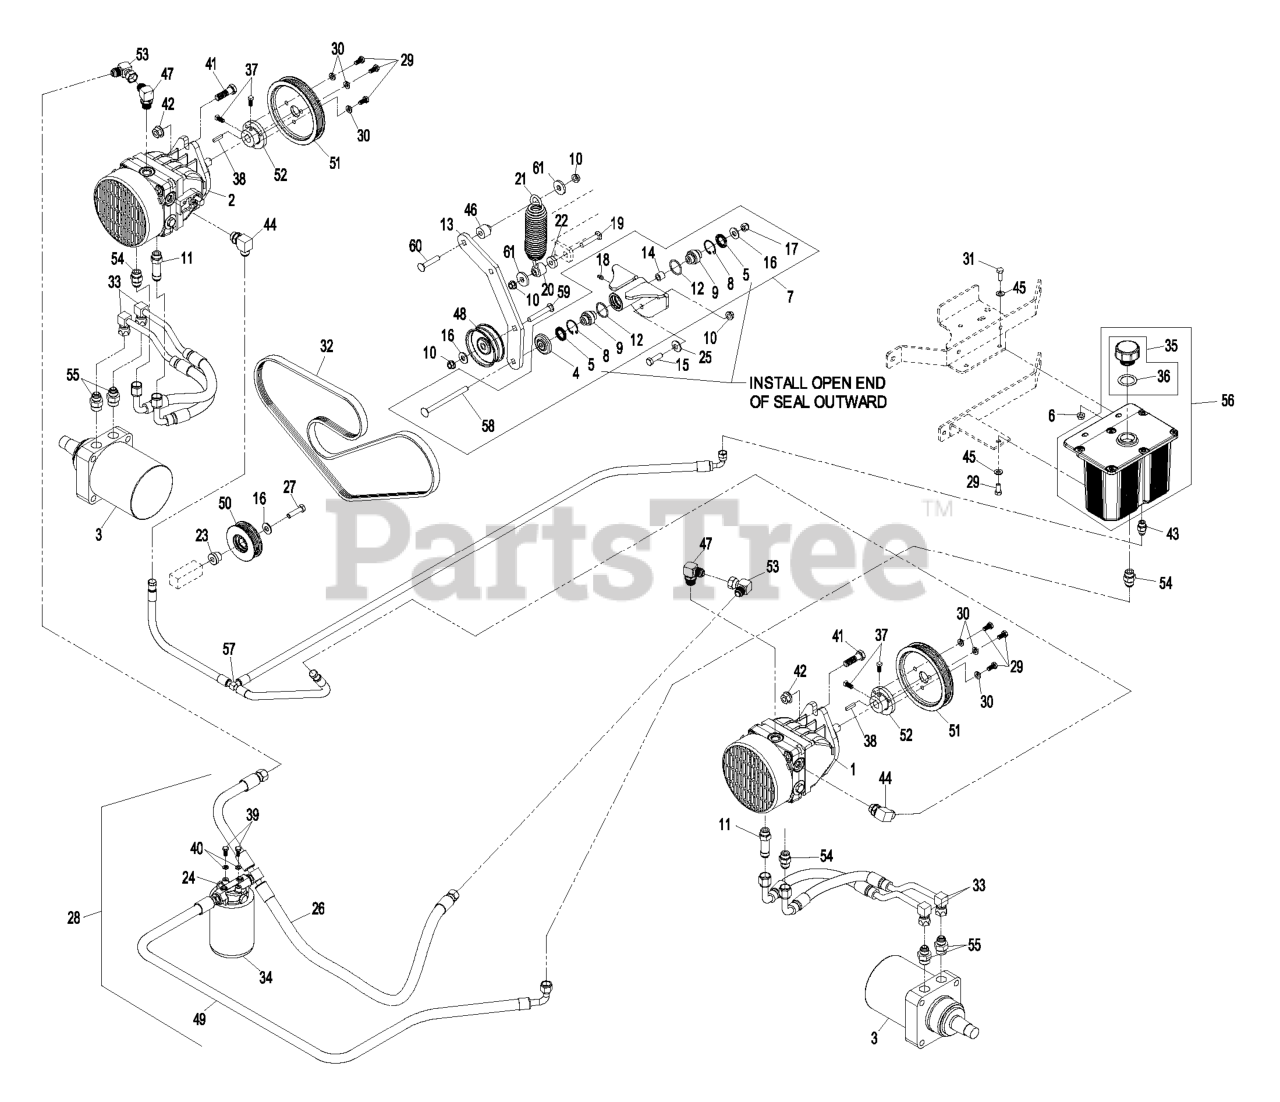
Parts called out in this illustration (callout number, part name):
4	GUARD-TOP
5	SEAL-LIP, SINGLE
7	KIT,XS PUMP IDLER
8	RING-SNAP
9	BEARING-SPHERICAL
10	NUT-HHF, WHIZ
11	ADAPTER-STR, LONG
13	ARM, XS HYDRO TIGHTENER
15	SCREW-HH
16	WASHER-FLAT
17	NUT-LOCK, NI
18	FITTING-GREASE
19	BOLT-CARR, SHORT NECK
20	SPACER-SPRING, FAN PUMP
22	SPACER-BRACKET, GUIDE
23	SPACER,LOWER FRAME IDLER
24	HEAD-FILTER
25	WASHER-BELLEVILLE
26	HOSE,31 EPS PUMP INLET
27	SCREW-HH
29	SCREW-HH
30	WASHER-LOCK
31	SCREW-HH
32	BELT,PVK 5 X 70.5
33	HYD HOSE ASM
34	FILTER,XP HYD 25 MICRON
35	KIT,HYD RES CAP W/GASKET
36	GASKET-CAP
37	SCREW-SET
39	SCREW-HH
40	WASHER-LOCK
41	SCREW-HH
42	NUT-HHF
43	FITTING-STRAIGHT
44	FITTING-ELBOW, 90 DEG
45	WASHER-PLAIN
47	FITTING-90 DEG
48	IDLER,PUMP
50	ASM,LOWER FRAME IDLER
51	SHEAVE,5K 5.6" PD POLY-V
52	HUB-PUMP
53	FITTING-90 DEG
54	FITTING-STRAIGHT
55	FITTING-STRAIGHT
56	HYDRAULIC TANK ASM
57	ASM,CASE DRAIN HOSE
58	BOLT CARR 3/8-16X5
59	SCREW-CARR
60	SCREW-CARR
